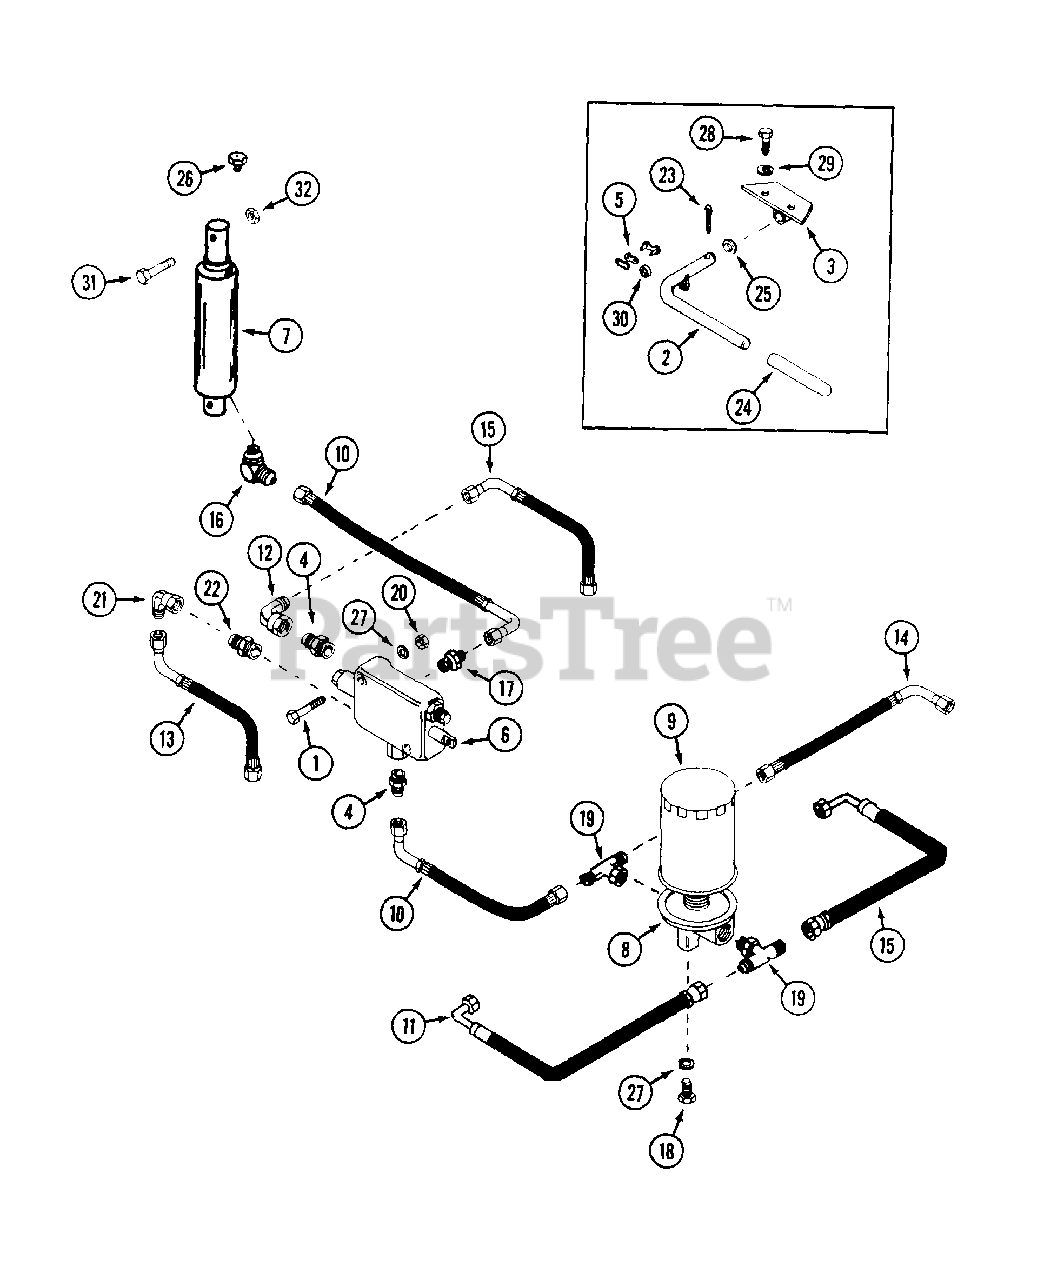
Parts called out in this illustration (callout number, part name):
1	BOLT - 1/4" - 20 x 2"
2	LEVER - actuator
3	PIVOT - lever
4	FITTING - 9/16" x 3/4"
5	CONNECTING LINK - #50
6	VALVE - lift
7	CYLINDER - lift
8	HOUSING - oil filter
9	ELEMENT - oil filter
10	HOSE - 3/8" ID x 26" long
11	HOSE - 3/8" ID x 31" long
12	FITTING - 90° 9/16"
13	HOSE - 90°, 3/4" x 19"
14	HOSE - 3/8" ID x 11.5" long
15	HOSE - 3/8" ID x 21" long
16	FITTING - 90° male tube adp.
17	FITTING - straight
18	BOLT - 1/4" - 20 x 5/8"
19	FITTING - tee
20	NUT - 1/4" - 20
21	FITTING - 90°, 3/4"
22	FITTING - straight
23	PIN - cotter 1/8" x 1"
24	GRIP - handle
25	GROMMET - lever
27	LOCKWASHER - 1/4"
28	BOLT - 5/16" - 18 x 1/2"
29	LOCKWASHER - 5/16"
31	BOLT - 1/2" - 13 x 2-1/2"
32	NUT - 1/2" - 13 lock
